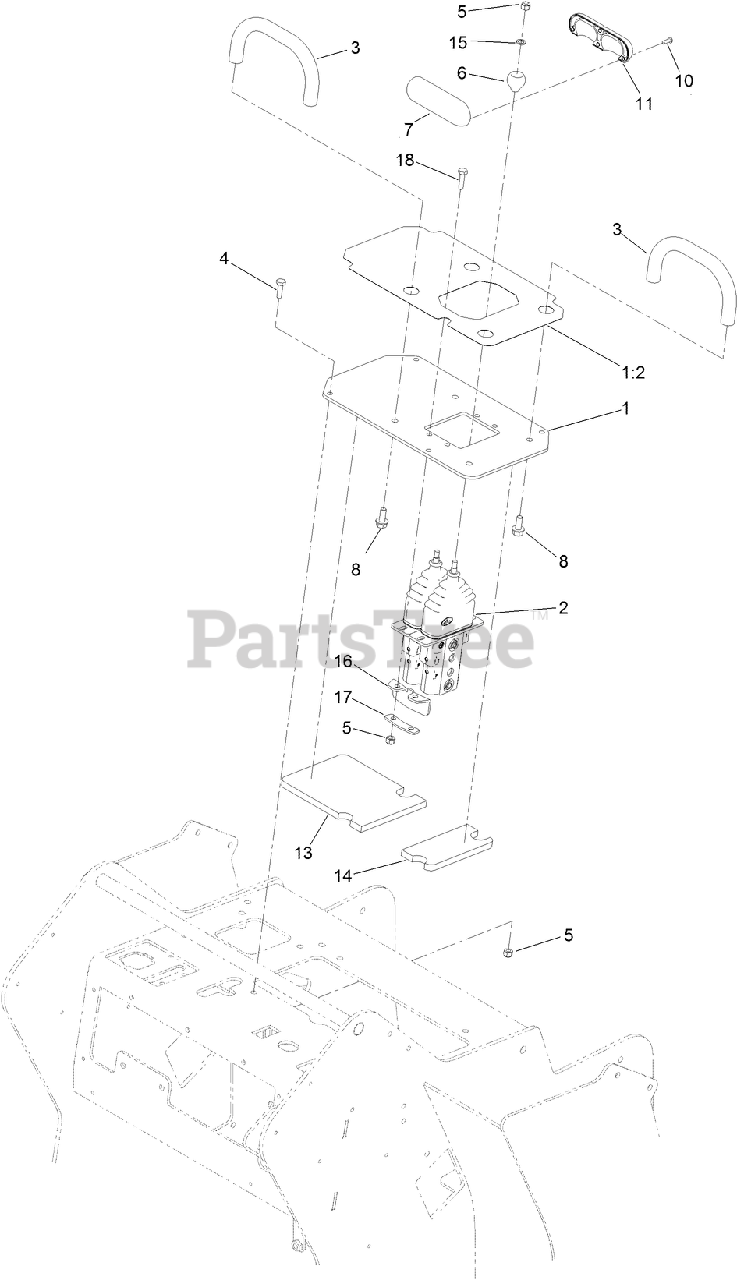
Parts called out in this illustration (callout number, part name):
1	PLATE-CONTROL
1:2	DECAL-CONTROL PANEL
2	VALVE-CONTROL
3	BAR-REFERENCE
4	SCREW-HH
5	NUT-LOCK, NI
6	BALL-TRACTION
7	HANDLE-CONTROL
8	SCREW-HHF
10	SCREW
11	HANDLE-TRACTION
13	FOAM-SHIELD, HEAT
14	FOAM-SHIELD, HEAT
15	SPACER-BEARING
16	COVER-RUBBER
17	PLATE-CLAMP
18	SCREW-HH
